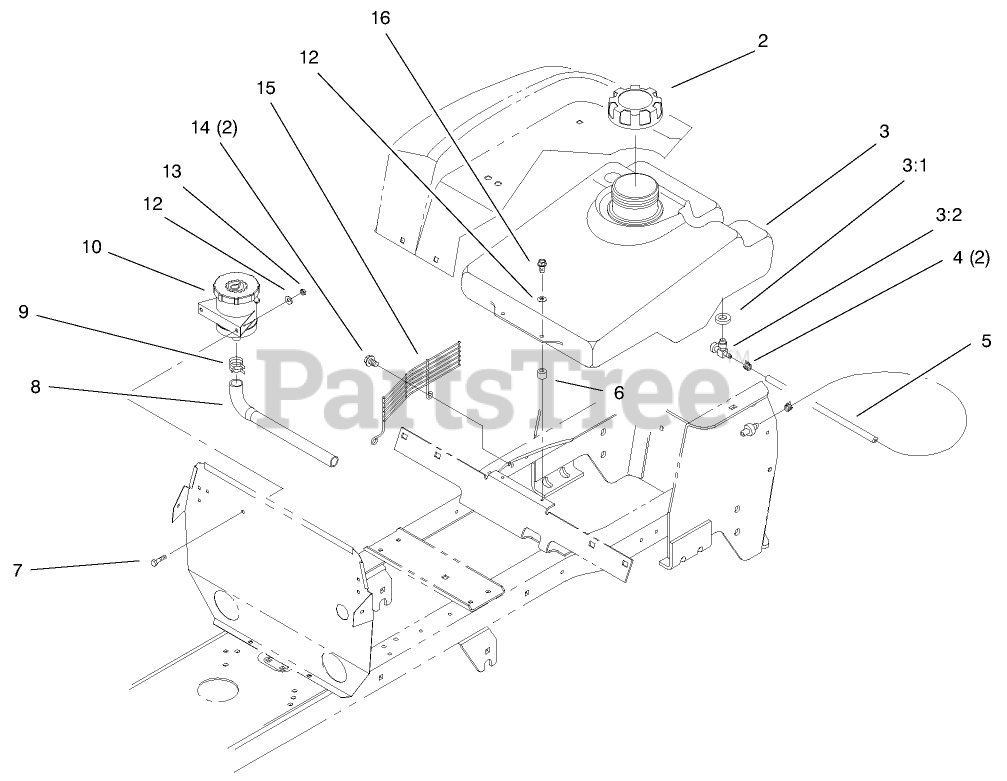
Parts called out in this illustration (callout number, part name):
2	GAS CAP ASM
3	TANK-GAS (FG50538)
3:1	VALVE-FUEL
4	CLAMP-HOSE
6	SPACER - FUEL TANK
7	SCREW-HH
8	HOSE - HYDRO
9	CLAMP-HOSE
12	WASHER-FLAT
13	NUT-LOCK, NI
14	SCREW-HWHTF
16	SCREW-HH
